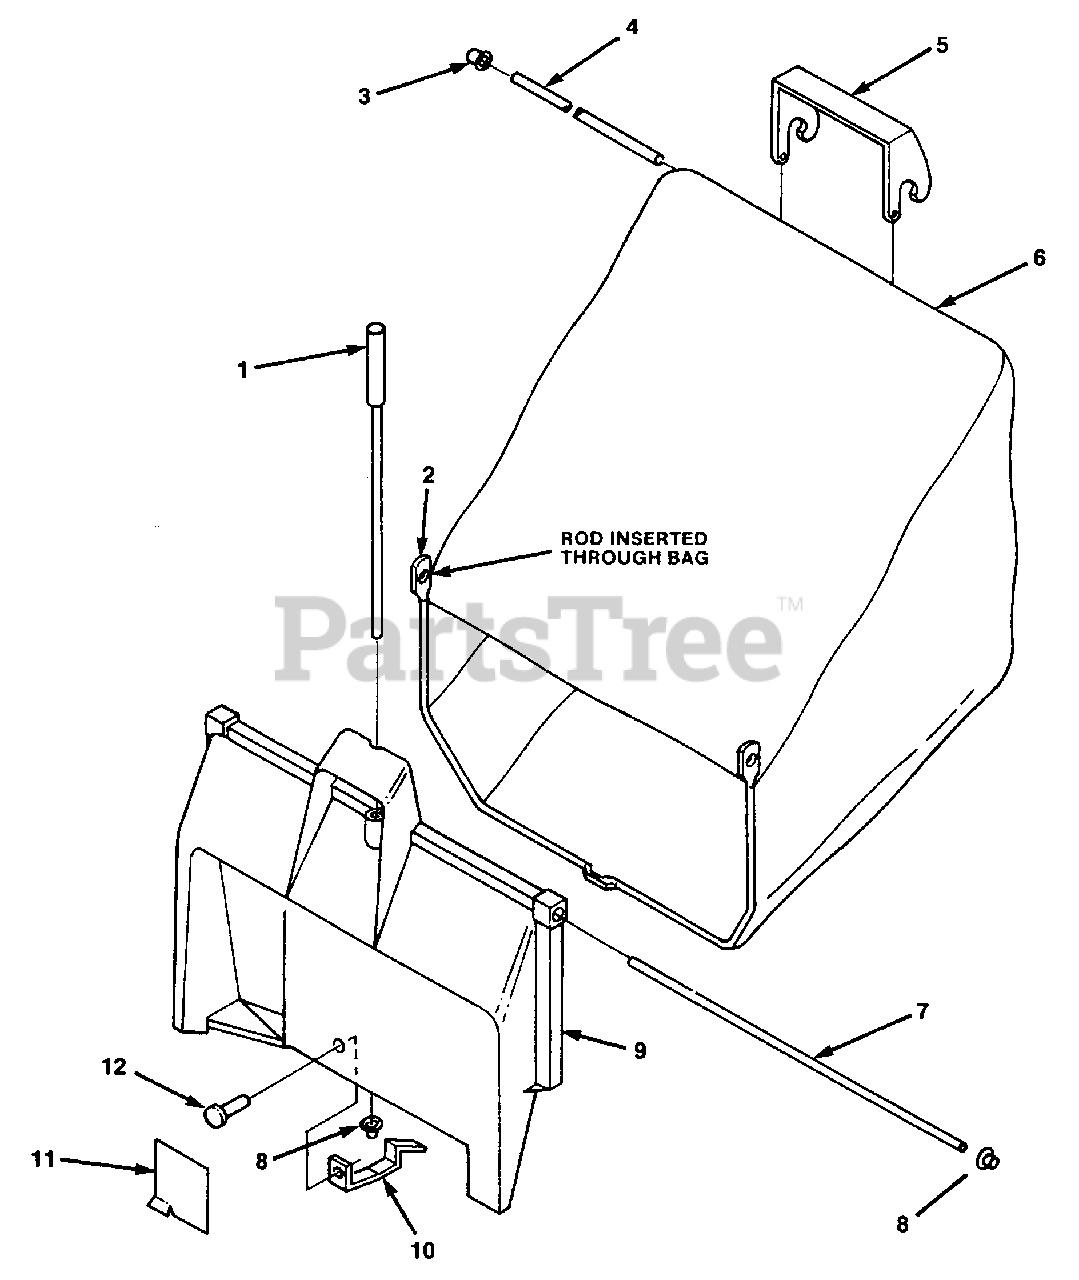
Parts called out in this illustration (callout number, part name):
1	LATCH- Rod
2	ROD- ZP Bag support
4	ROD- Upper bag
5	HANDLE- Upper bag
6	CATCHER- Grass
7	ROD- Bag hinge
9	ADAPTOR- Bag
11	DEFLECTOR
12	RIVET- (5/32 x 3/8")
